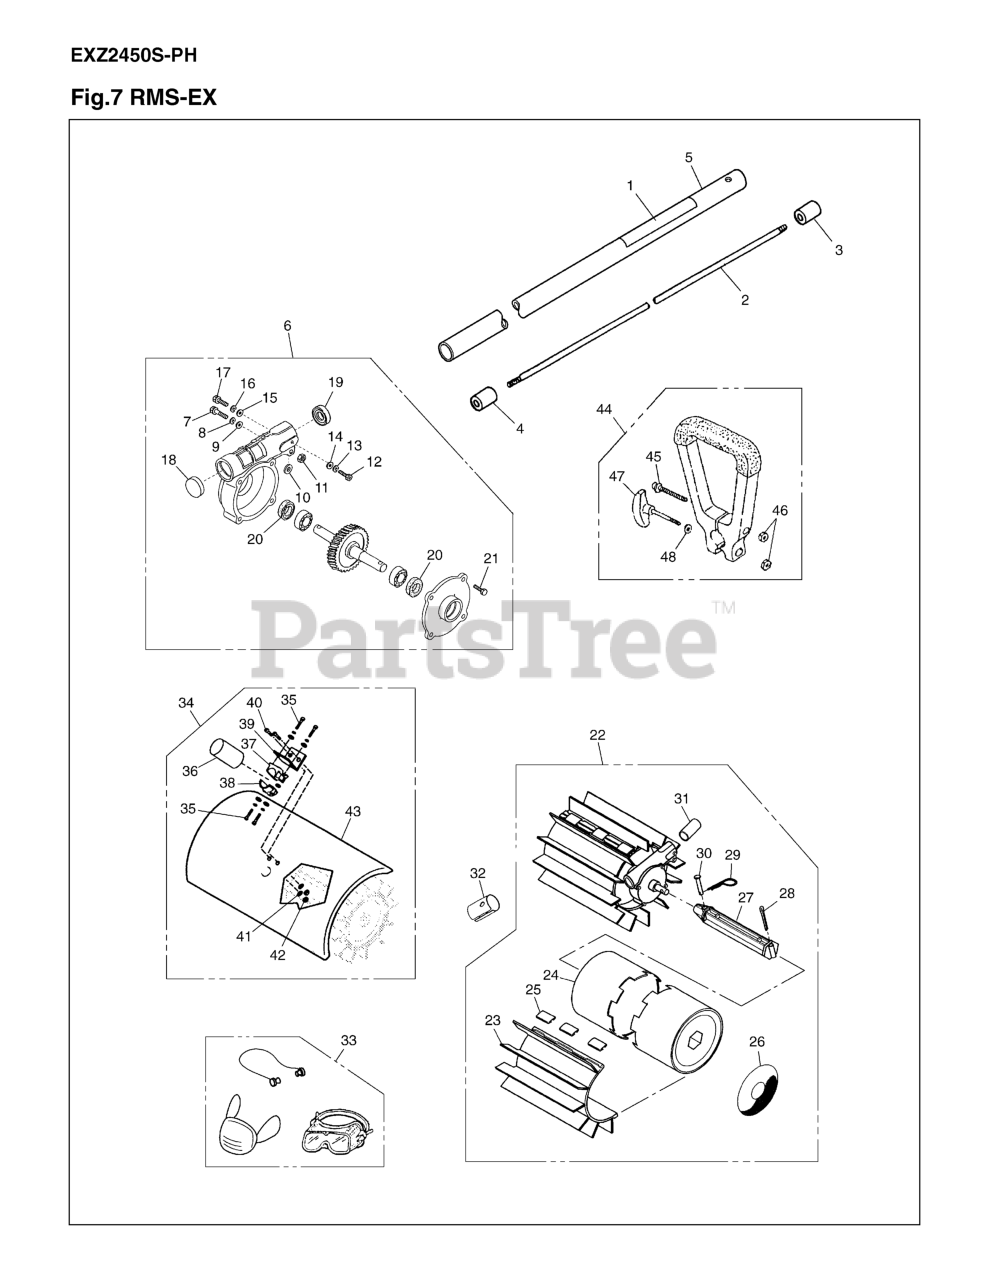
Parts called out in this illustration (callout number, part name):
1	PIPE COMP
2	SHAFT
3	SHAFT-JOINT
4	SPACER
5	PLATE-NAME
7	BOLT
8	SPRING WASHER
9	WASHER, FLAT
10	WASHER, FLAT
11	NUT, M6 X 5
12	BOLT
13	WASHER
16	WASHER
17	SCREW
18	PLUG, HOUSING
21	SCREW
22	SWEEPER ASSY
25	CLIP, BELT
26	LABEL, REDMAX
27	DRUM AXLE
28	PIN, COTTER
29	PIN, HITCH
30	CLEVIS PIN
31	PROTECTOR, TUBE
33	SAFETY KIT
34	DEBRIS SHIELD ASSEMBLY
37	BRACKET, HANDLE
38	CAP, LOWER
39	BRACKET, SHIELD
44	HANDLE ASSY
